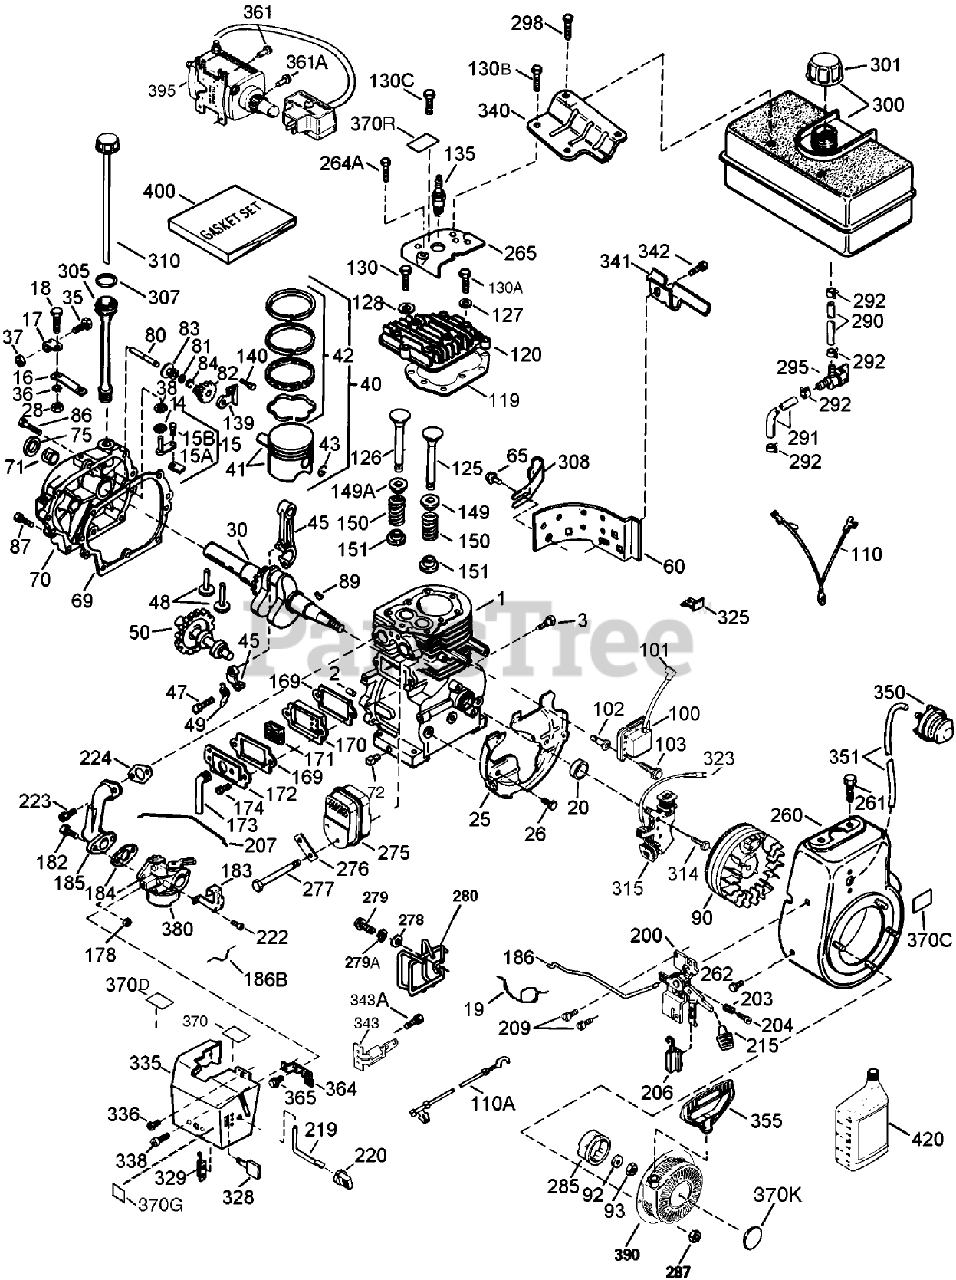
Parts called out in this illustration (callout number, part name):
186	Link-Governor
186B	Spring-Choke
200	Bracket-Control (Includes 19, 203, 204, 206)
203	Spring-Compression
204	Screw (T-10, 5-40x7/16)
206	Terminal
207	Link-Throttle
209	Screw (10-32 x 1/2)
215	Knob-Control
219	Rod-Choke
220	Knob-Control
222	Screw (10-32 x 1/2)
223	Screw (T-30, 5/16-18x1-3/32)
224	Gasket-Pipe, Intake
260	Housing-Blower
261	Screw (5/16-18x3/4)
262	Screw (5/16-18x9/16)
264A	Screw (1/2-20x5/8)
265	Cover-Head, Cylinder (Black)
275	Muffler
276	62513 SNWTHWR W/284
277	Screw (5/16-18x4-3/16)
278	Washer-Flat
279	Screw (10-16 x 47/64)
279A	washer-Lock
280	Muffler Heat Shield ASM (Includes 278, 279, 279A)
285	Cup-Starter
287	Nut and Lock Washer (1/4-28)
290	Line-Fuel (8.62)
291	Line-Fuel
292	Clamp-Line, Fuel
295	Valve-Shut Off, Fuel
298	Screw (1/4-15x7/8)
300	Tank-Fuel (Includes 292, 301)
301	Cap-Fuel
305	Tube-Fill, Oil
307	O-Ring
308	Clip-Tube, Fill
310	Gauge Oil ASM
314	Screw (1/4-20 x 3/4)
315	Coil-Alternator, 18 Watt (Includes 323)
323	Terminal
325	Clip-Wire
328	Key-Ignition
329	Terminal
335	Cover-Carburetor (Black)
336	Screw (10-32x1/2)
338	Screw (10-32 x 3/8)
340	Bracket-Tank, Fuel
341	Bracket-Tank, Fuel (Black)
342	Screw (1/4-20x19/32)
343	Bracket-Switch, Key
343A	Screw (8-32 x 23/64)
350	Primer ASM
351	Line-Primer
355	Handle-Starter, Mitten Grip
361	Screw (T-30, 1/4-20x15/32)
361A	Screw
364	Bracket-Cover, Carburetor
365	Screw (8-32x27/64)
370	Decal-Lubrication
370C	Decal-Primer, International Symbol
370D	Decal-Instruction
370G	Decal-Speed Control and Choke
370K	Decal-Tecumseh Logo for Top of Recoil Starter
370R	Decal-Warning (Bilingual)
380	Carburetor (Incl. Ref.# 184)
390	Starter-Rewind
395	Electric Starter Motor ASM (220 Volt)
400	Gasket Set (Incl. items marked *)
420	Oil-Engine, S A E 5W30
